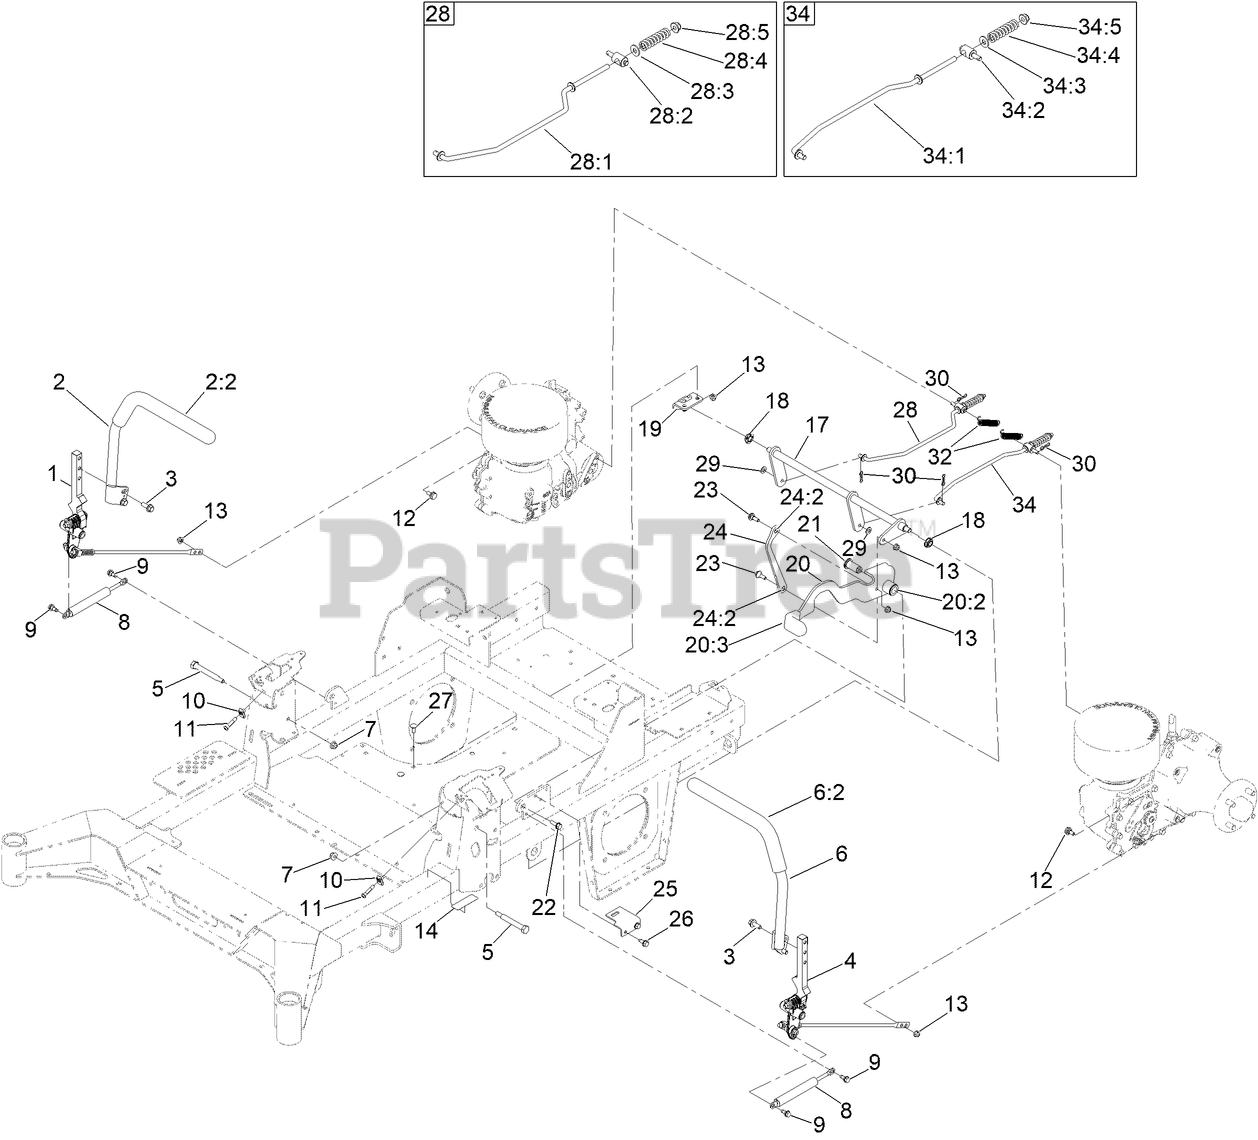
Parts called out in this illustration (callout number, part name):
1	MOTION CONTROL ASM-RH
2	HANDLE ASM - RH
2:2	GRIP-CONTROL, LEVER
3	SCREW-HHF
4	MOTION CONTROL ASM-LH
5	BOLT-PIVOT
6	HANDLE ASM - LH
6:2	GRIP-CONTROL, LEVER
7	NUT-HF, NI
8	DAMPER
9	SCREW-SHOULDER
11	SCREW-HSBH
12	BOLT-SHOULDER,HFH
13	NUT-HF, NI
14	DECAL-BRAKE, PARKING
17	BRAKE ASM
18	BEARING-SPHERICAL
19	BRACKET-BRAKE
20	BRAKE LEVER ASM W/GRIP
20:2	BUSHING-FLANGE
20:3	GRIP-LEVER
21	PIVOT-HANDLE
22	SCREW-HHF
23	SCREW-SHOULDER
24	BRAKE LINK ASM
24:2	BUSHING-SLEEVE
25	PLATE-SWITCH
26	SCREW-HWHTF
27	SCREW-CARR
28	RH BRAKE ROD ASM
28:1	ROD-BRAKE, RH
28:2	FITTING-ROD
28:3	WASHER-FLAT
28:4	SPRING-COMPRESSION
28:5	NUT-HF, NI
29	WASHER-FLAT
30	PIN-COTTER, LOCKING
32	SPRING-EXTENSION
34	LH BRAKE ROD ASM
34:1	ROD-BRAKE, LH
34:2	FITTING-ROD
34:3	WASHER-FLAT
34:4	SPRING-COMPRESSION
34:5	NUT-HF, NI
